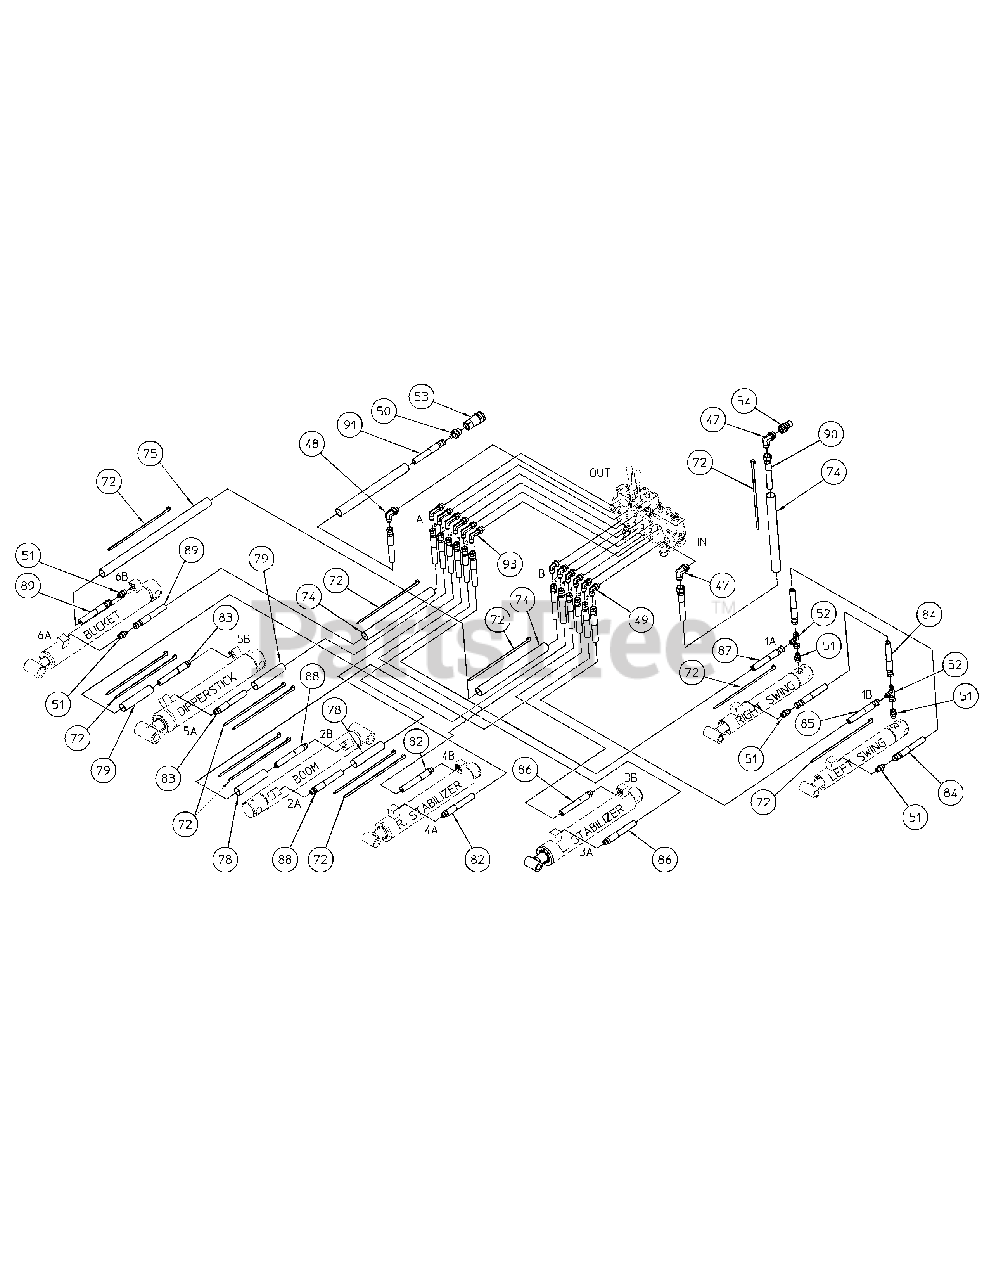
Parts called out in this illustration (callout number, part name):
47	ADAPTER FLARE
48	ADAPTER FLARE
49	ADAPTER FLARE
50	ADAPTER FLARE
51	ADAPTER FLARE
52	SWIVEL NUT RUN TEE
53	COUPLER BODY
72	PLASTIC TIE BLACK
74	HOSE SLEEVE, 1 X 30
75	HOSE SLEEVE, 1 X 19
78	HOSE SLEEVE, 1 X 67
79	HOSE SLEEVE, 1 X 89
82	HOSE 1/4ID X 42"
83	HOSE 1/4ID X 85"
84	HOSE 1/4ID X 20"
85	HOSE 1/4ID X 26"
86	HOSE 1/4ID X 40"
87	HOSE 1/4ID X 34"
88	HOSE 1/4ID X 63"
89	HOSE 1/4ID X 107"
90	HOSE 3/8ID X 54"
91	HOSE 3/8ID X 34"
93	ADAPTER FLARE
